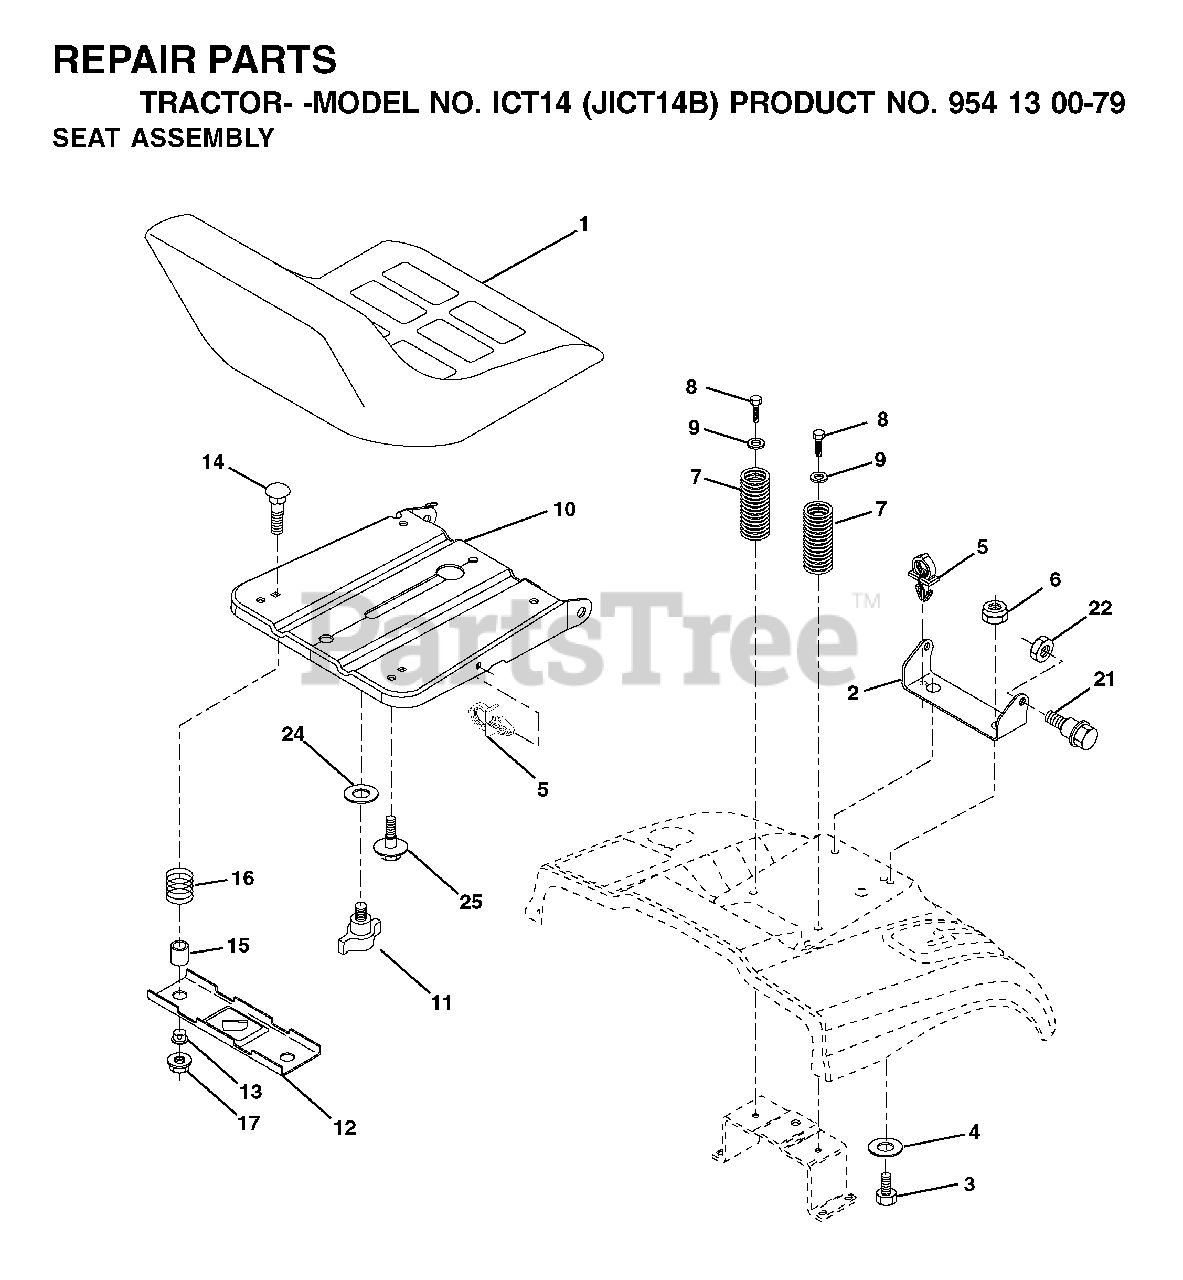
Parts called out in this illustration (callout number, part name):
2	SEAT PIVOT BRKT
5	PUSH CLIP
7	SPRING COMPRESSION
8	SCREW 3/8-16X1
9	WASHER
10	PAN, SEAT
11	KNOB.SEAT.ADJ.WINGNUT
12	BRKT SWITCH
14	BOLT.ROUND.HEAD.SQUARE.NECK
15	SPACER SPLIT 28X.96
17	NUT T
21	BOLT.SHOULDER.5/16-18
22	NUT.71038.31-18.HEX.NYLOCK
25	BOLT,SHOULD
